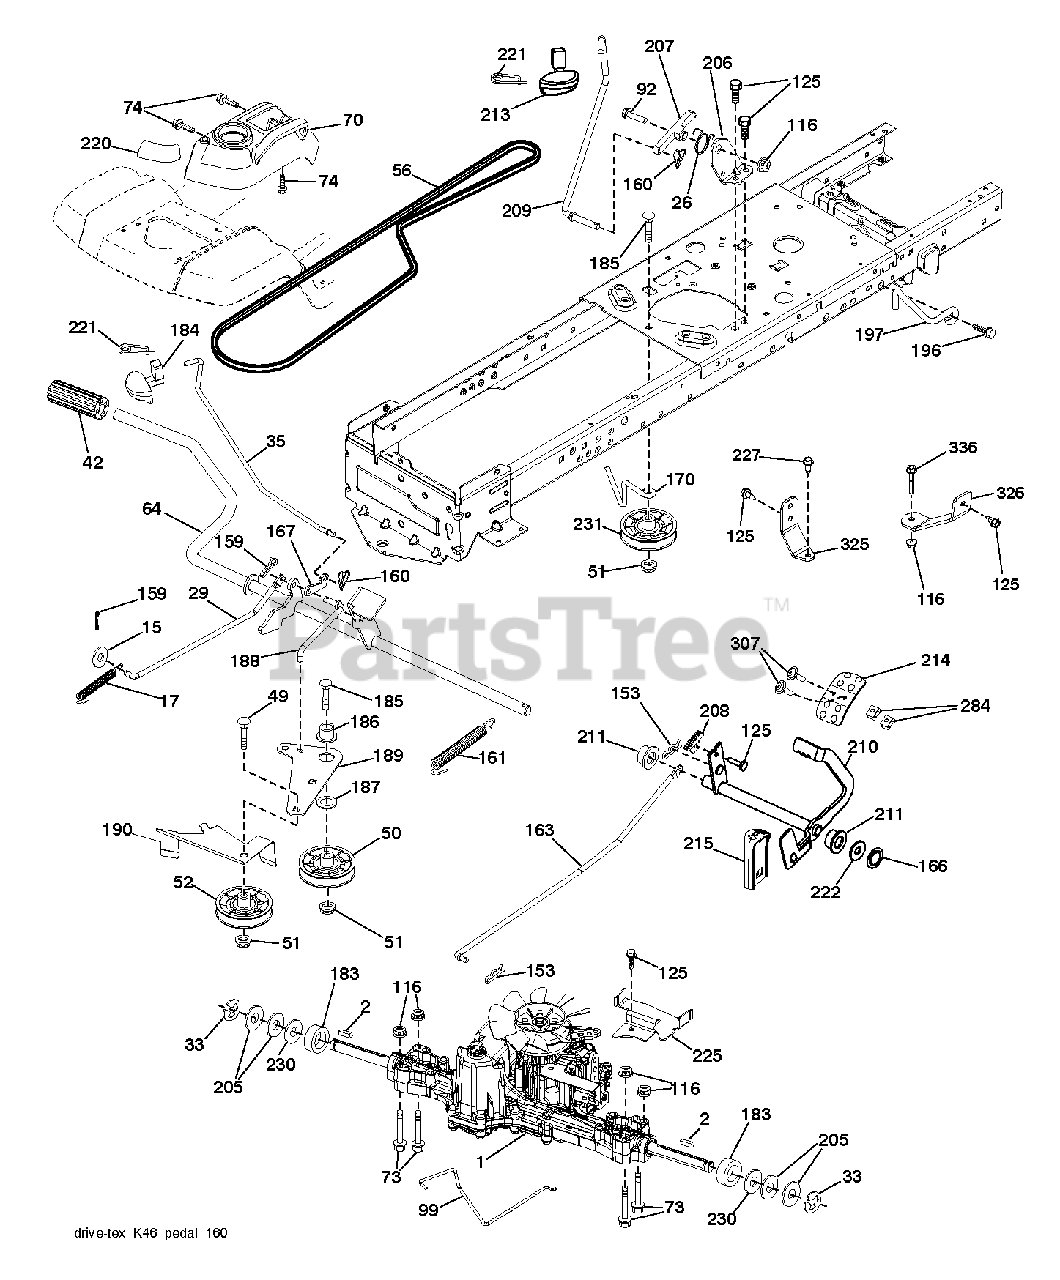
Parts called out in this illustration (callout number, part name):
2	SQUARE KEY
15	WASHER
17	SPRING.BRAKE.K46.GREEN
26	SPRING.RETURN.CRUISE
29	ROD.BRAKE.K46
33	E RING HYT
35	ROD .BRAKE. PARKING. GT. HUSQ.
42	PEDAL COVER T
50	IDLER.FLAT.910.OFFSET
51	NUT LOCK FLG 3/8-16 UNC
52	IDLER.V-GROOVE.910.OFFSET
56	V-BELT.MOWER.92.40.42/K46
64	SHAFT.ASM.PEDAL.BRK.CNTR
70	CONSOLE.ASM.RH.GT.FC.HUSQ
73	BOLT
74	SCREW.HI-LO.CONSOLE
92	BOLT
99	ROD.SPRING.BYPASS.K46.LT.Z
116	NUT LOCK HEX FLANGE 5/16-18
125	SCREW
153	RETAINER M
159	COTTER PIN
160	RETAINER CLIP
161	SPRING, RETURN LT
163	ROD.CONTROL.K57R.K46
166	NUT.PUSH.625
167	LATCH.BRAKE.SPRING
170	KEEPER.CENTER SPAN.1.688
183	SPACER AXLE
184	HANDLE.PARKING.BRAKE.H (BLK)
186	SPACER.RETAINER
187	WASHER 12/32X2X10GA
188	RP LINK.CLUTCH.GROUND.DRIVE
189	BELLCRANK.GROUND.DRIVE.TEX.
190	KEEPER.BELLCRANK.DRIVE
196	SCREW 3/8-16X1
197	BRKT.42.FCS.CLUTCH.ANTIROTATIO
206	BRACKET.MOUNT.CRUISE.LATCH
207	LATCH.CONTROL.CRUISE.TEX
208	GEAR.SECTOR.CONTROL.CR
209	ROD.CONTROL.CRUISE.GT.
210	ROCKER.ASM.PEDAL.CONTR
211	BEARING.NYLON
213	KNOB.CONTROL.CRUSIE.HU
214	PEDAL.FORWARD.HUSQVARNA.DEALER
215	PEDAL.COVER.REVERSE.CRD.X428BK
220	REFLECTOR.RH.TEX GT
221	RETAINER.SPRING.CLIP.H
222	WASHER 21/32 X 1-1/4 X 10 GA.
225	KEEPER.BELT.TRANSAXLE.K46
227	SCREW
230	WASHER.HARDENED
231	IDLER.V-GROOVE.1.688.OFFSET
284	NUT.U-CHNL.1/4-20.550DP.350PNL
307	SCREW.MACHINE.CR.1/4-20
325	TORQUE.STRAP.K46.LT.LH
326	BRACKET.TRQ.STP.K46.18"TIRE.RH
336	BOLT.5/16-18X1-3/4.FLANGED.HEX
